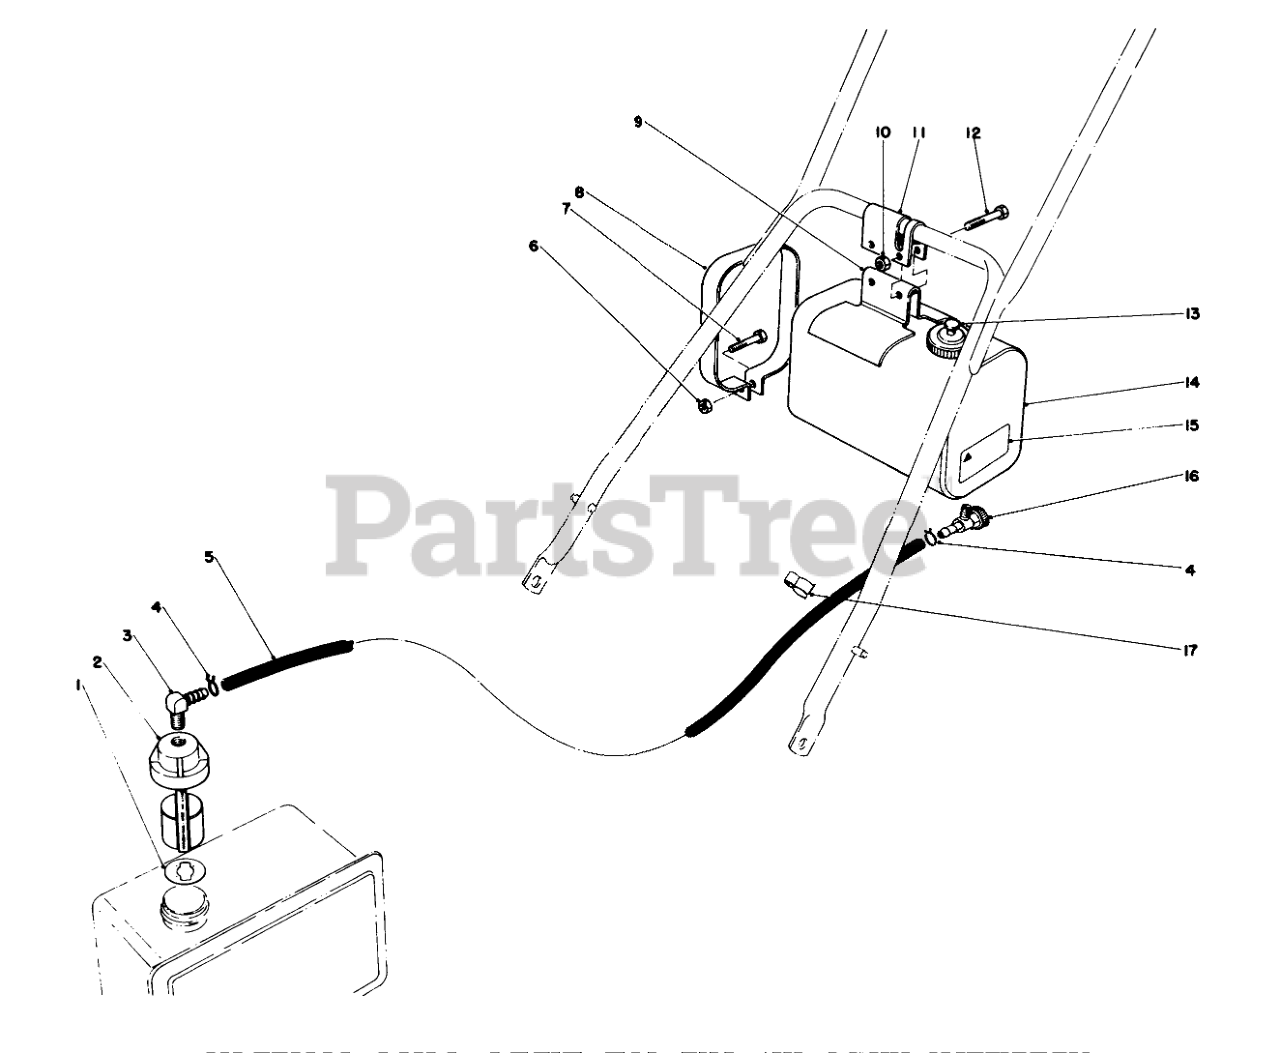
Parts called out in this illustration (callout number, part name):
1	GASKET
2	Fuel Control Valve (Incl. Ref. #1)
3	CONNECTOR-HOSE
4	Clamp
5	FUEL LINE
6	NUT-LOCK
7	SCREW-HH
8	TANK STRAP
9	FUEL TANK BRACKET
10	Nut
11	Clamp
12	SCREW-HH
14	Fuel Tank (Incl. Ref. #13 & 15)
15	Decal-Caution
16	.125 ID SHUTOFF VALVE
17	CLAMP
